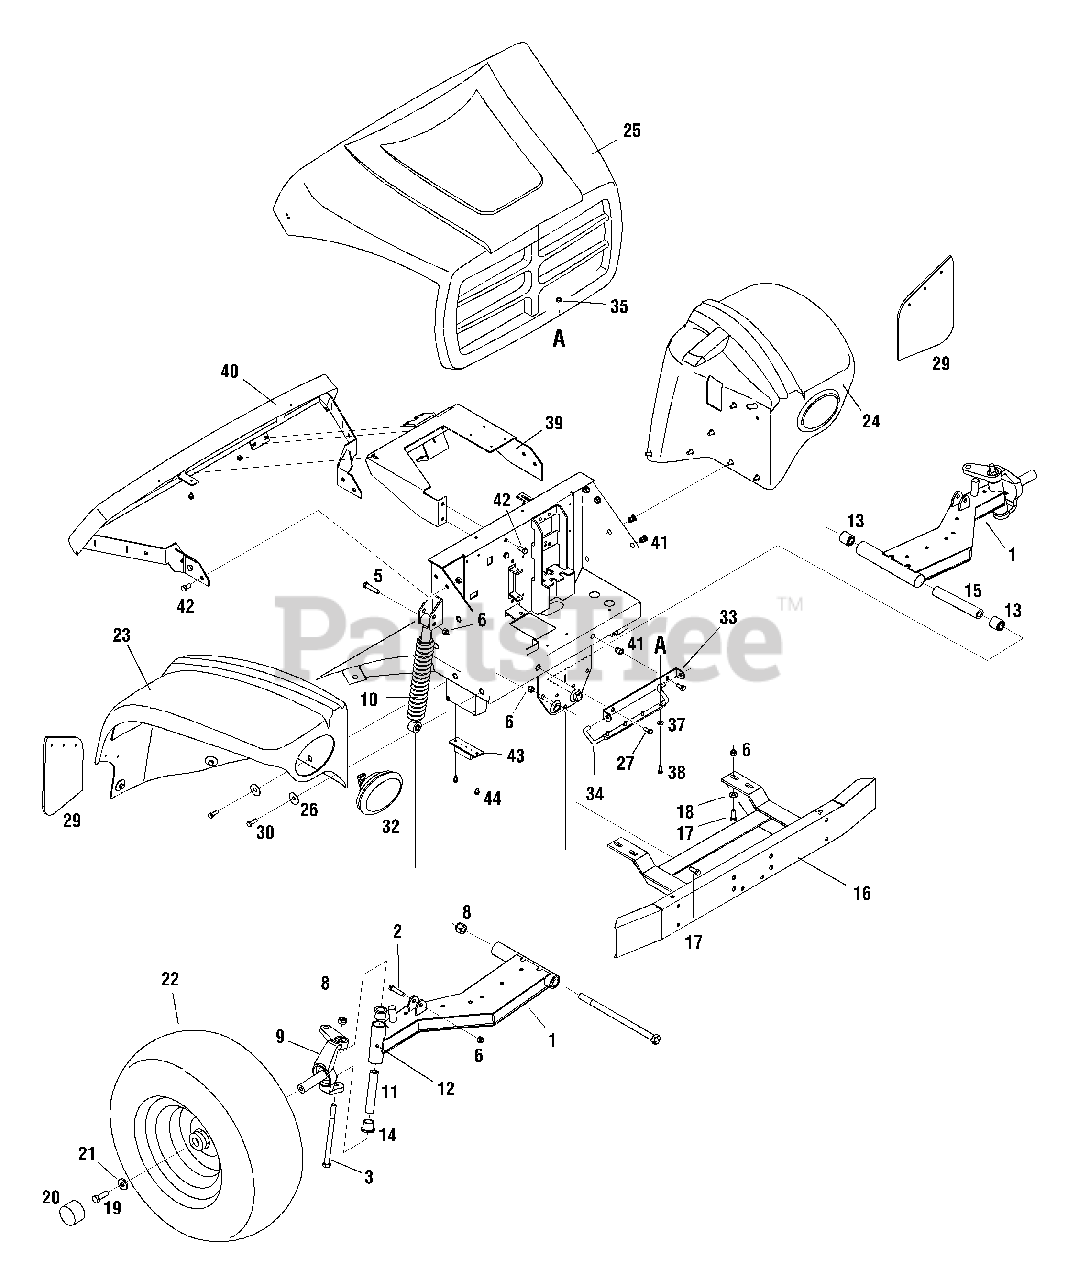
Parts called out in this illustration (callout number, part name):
1	Axle Assembly, Right-front
2	Hex Screw, 3/8-16 x 1.75
3	Hex Screw, 1/2-13 x 7.0, Gr5
4	Hex Screw, 5/8-11 x 11.13, Gr5
5	Hex Screw, 3/8-16 x 2.25
6	Nut, Hex Lock, Nylon, 3/8-16, Gr5
7	Nut, Hex Lock, Nylon, 5/8-11, Gr5
8	Nut, Hex Lock, 1/2-13
9	Steering Control Knuckle, RH
10	Shock Absorber, 2.9 Stroke
11	Tube, .875 x .50 x 4.75
12	Grease Fitting
13	Bearing, .63 ID x 1.19 OD
14	Bushing, Steering
15	Spacer, .645 ID x 1.063 OD
18	Flat Washer, .406 x .875 x .059
19	Hex Screw, 1/2-13 x 1.50, Gr5
21	Flat Washer, .531 x 1.25 x .181
22	Wheel Assembly, 22.5 x 10 x 8, Turf
23	Panel Assembly, Right Fender, Yellow
24	Panel Assembly, Left Fender, Yellow
25	Panel Assembly, Hood, Yellow
26	Hex Screw 5/16-18 x 1.00 Gr 5
27	Hex Screw, 5/16-18 x .75
28	Flat Washer, .350 x 1.25 x .06
30	Washer, Bell, .39 x 1.38 x .062
31	Flat Washer, .194 x .62 x .063
32	Headlamp Assembly
35	Nut, Hex Lock, 1/4-20
36	Cotter Pin, Internal, 1.42
37	Washer, Flat, .271 x .63 x .065
38	Hex Screw, 1/4-20 x .75
41	Insert Nut, 5/16-18
42	Hex Screw, 3/8-16 x .75
43	Screw, Self-tapping, 1/4-20 x .5
44	Suspension Bumper
